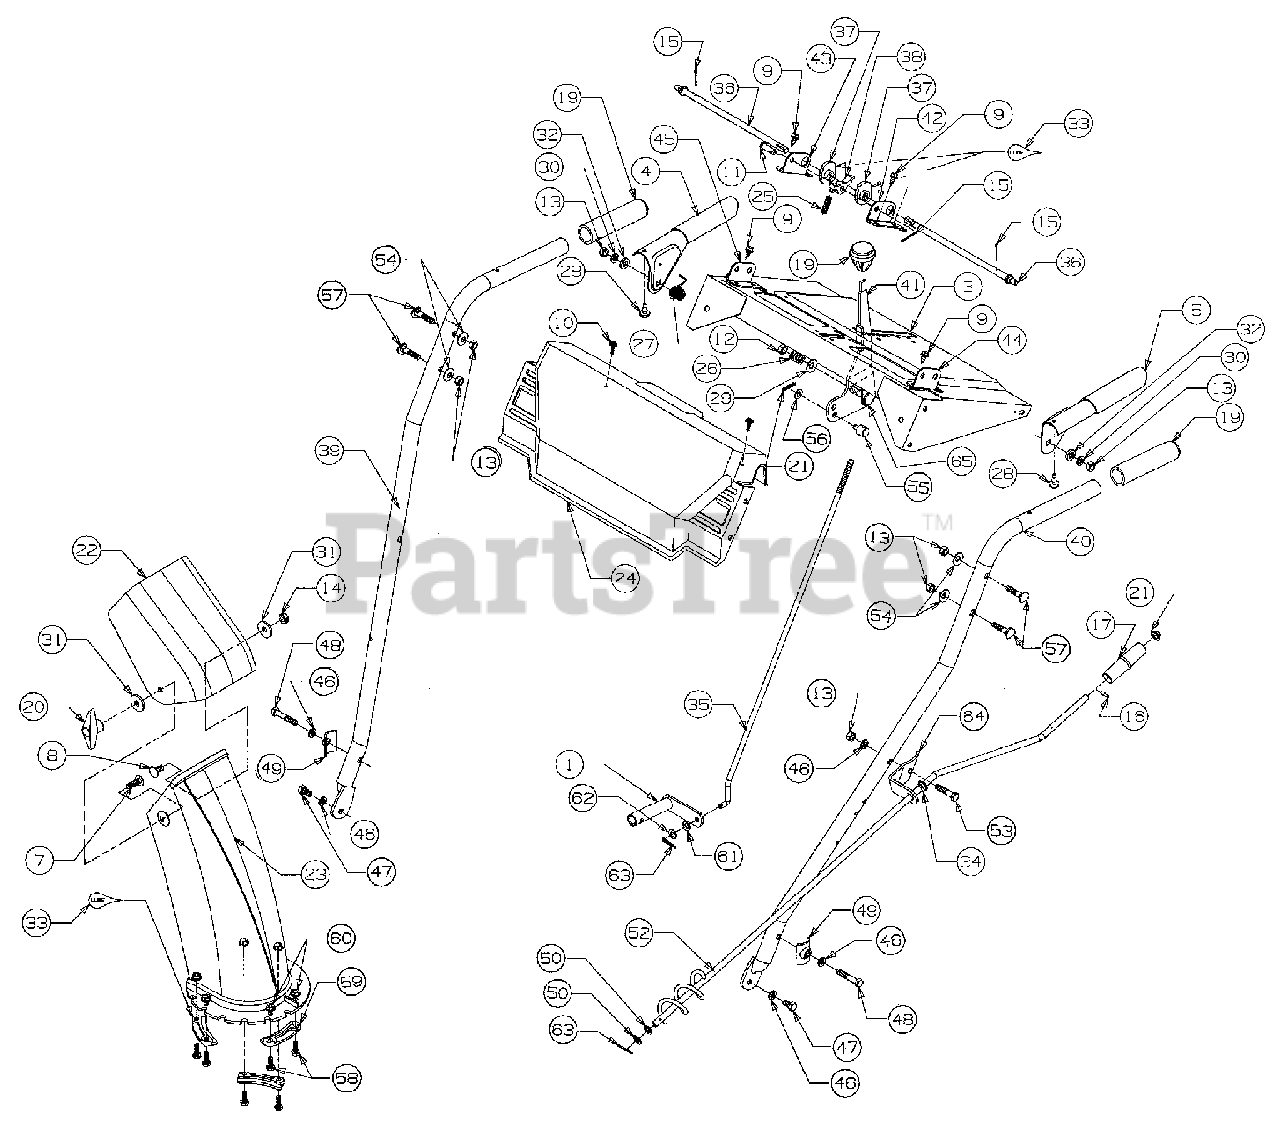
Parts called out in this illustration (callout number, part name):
5	Handle-Engagement-L.H.
7	Screw
8	Bolt-Carriage
9	Screw
10	Screw
11	Pin-Clevis
12	Nut-Hex
13	Nut-Hex
14	Nut-Lock
15	Pin-Cotter
16	Pin-Roll
21	Cap-Push
22	Chute-Upper
23	Chute-Lower
24	Panel-Handle
25	Spring
26	Spring
27	Spring
28	Bumper
29	Washer-Bell
30	Washer-Lock
31	Washer
32	Washer
33	Lubricant
34	Bushing-Plastic
35	Rod-Shift
36	Rod-Cam
37	Cam-Handle Lock
38	Pawl-Handle Lock
46	Washer-Lock
47	Screw
48	Screw
49	Tab-Handle
50	Washer-Flat
52	Crank-Chute
53	Screw
54	Washer-Bell
55	Ferrule
56	Washer-Flat
57	Bolt-Carriage
58	Screw
59	Keeper-Chute Flange
60	Nut-Lock
62	Washer-Flat
63	Pin-Cotter
